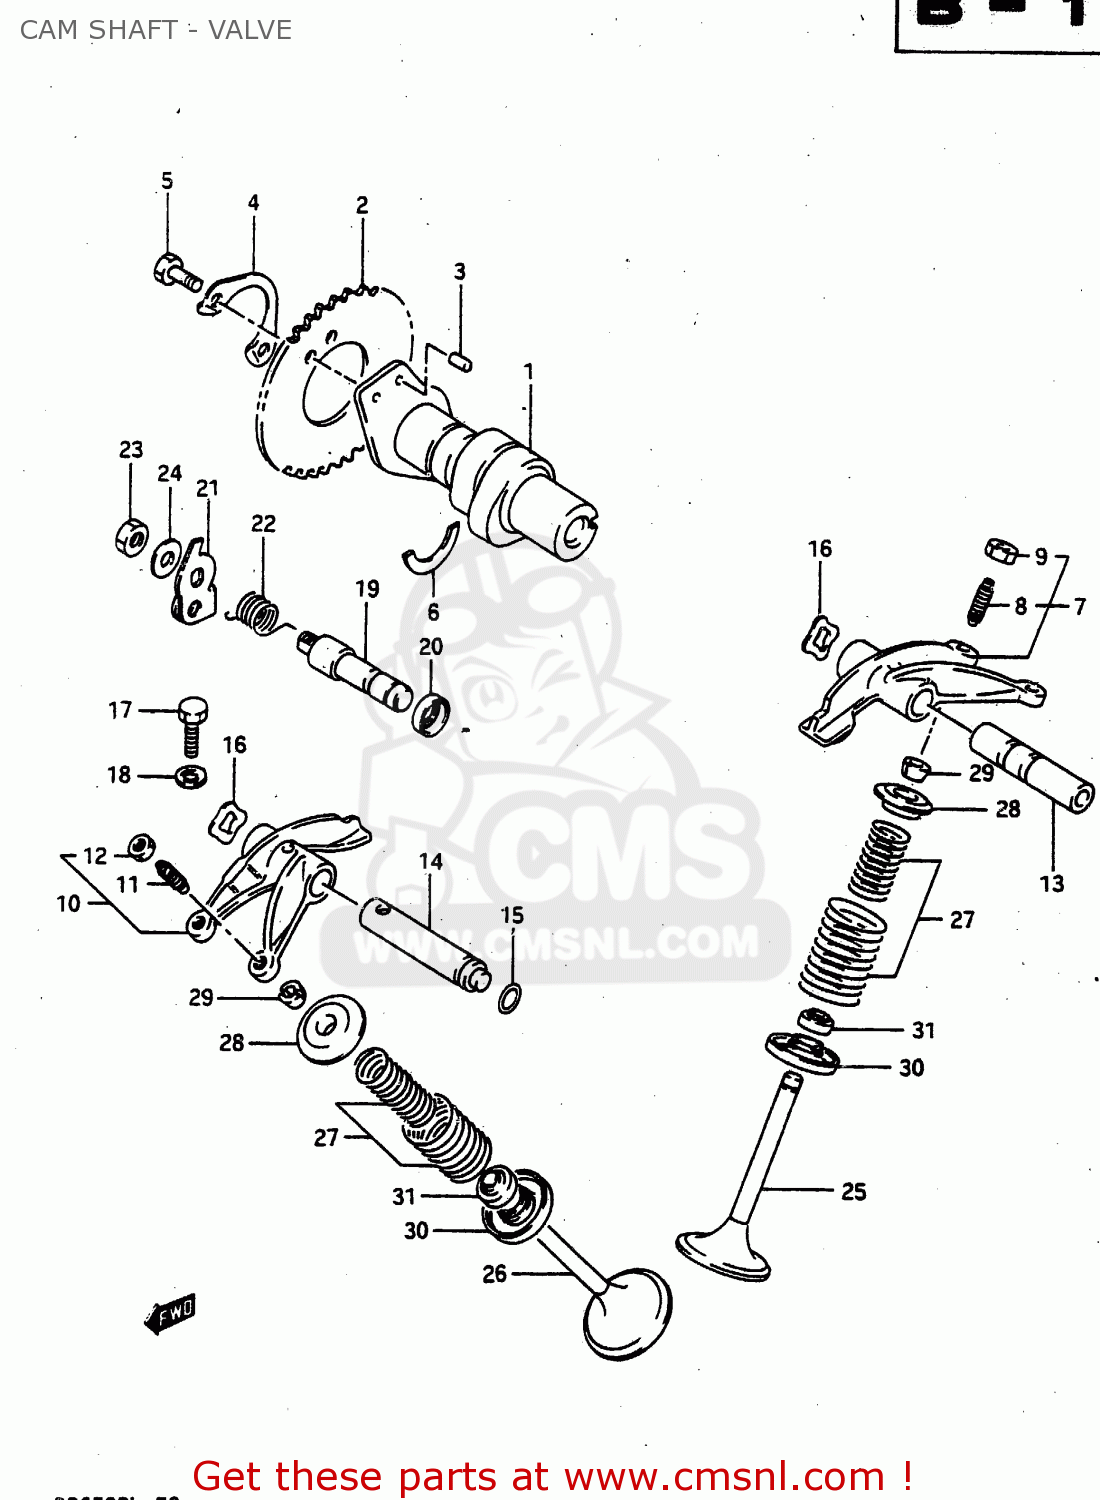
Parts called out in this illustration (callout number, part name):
1	CAMSHAFT
2	SPROCKET,CAMSHAFT(NT:42)
3	PIN
4	WASHER,CAM CHAIN SPROCKET
5	BOLT(6X12.5)
6	C RING
7	ARM,VALVE ROCKER INTAKE
8	SCREW,TAPPET ADJUSTING
9	NUT,ADJUSTING SCREW
10	ARM,VALVE ROCKER EXHAUST
11	SCREW,TAPPET ADJUSTING
12	NUT,ADJUSTING SCREW
13	SHAFT,VALVE ROCKER ARM INTAKE
14	SHAFT,EXHAUST VALVE ROCKER ARM
15	O RING(D:1.9,ID:8.6)
16	WASHER
17	BOLT 6X30
18	GASKET(5.8X13X1.2) (NAS)
19	SHAFT,DECOMPRESSION
20	SEAL,OIL(10X17X6)
21	LEVER,DECOMP SHAFT
22	SPRING,DECOMPRESSION SHAFT LEVER
23	NUT 8MM
24	WASHER
25	VALVE,INTAKE
26	VALVE,EXHAUST
27	SPRING SET,VALVE
28	RETAINER,VALVE SPRING
29	COTTER VALVE
30	SEAT,VALVE SPRING
31	SEAL,OIL(7X14.4X9)
